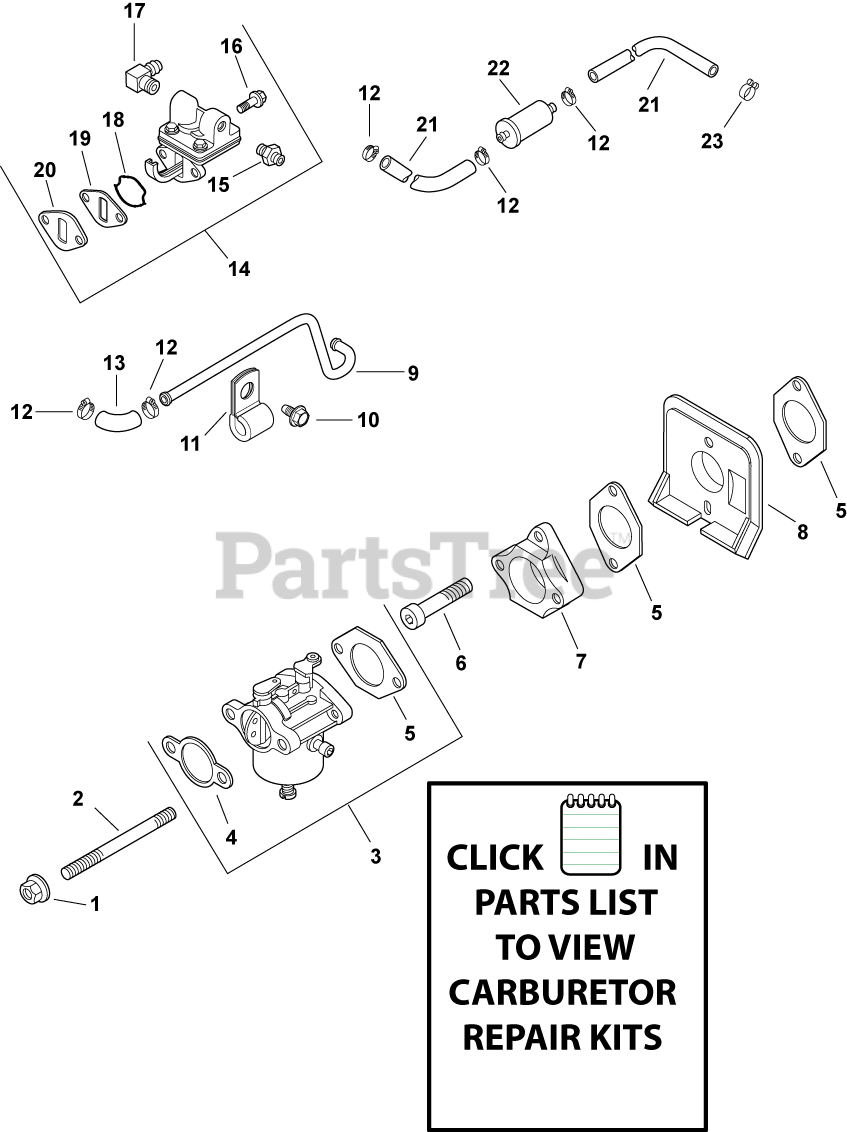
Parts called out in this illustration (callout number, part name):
1	NUT, FLG M6X1.0
2	STUD,M6X1.0X116
3	KIT, CARB W/GASKETS - USE 12 853 169-S
4	GASKET, AIR CLEANER BASE
5	GASKET, CARBURETOR
6	SCREW, SKT CAP M6X1.0X35
7	ADAPTER, CARBURETOR
8	DEFLECTOR, HEAT
9	LINE, FUEL - DISCONTINUED
10	SCREW, FLG THD FRM M5X.8X10
11	CLIP, TUBE & WIRING (KM)
12	CLAMP, HOSE (KM)-USE 25 237 31-S
13	HOSE, FUEL LOW-PERMEATION
14	KIT, FUEL PUMP
15	KIT, STRAIGHT FITTING
16	SCREW, LBD SKT M6x1.0x20-(#25086403S)
17	CONNECTOR, 90 DEG. HOSE
18	O-RING, FUEL PUMP
19	SPACER, FUEL TANK
20	GASKET, FUEL PUMP
21	HOSE,LW PERM.FUEL 24.00"-USE 25 111 81-S
22	FILTER,FUEL 51 MICRON (FUEL PUMP)
23	CLAMP, BAND SPRING HOSE-(#2523737S)
1285375-S	KIT, CARBURETOR W/GASKET - (#DSC)
